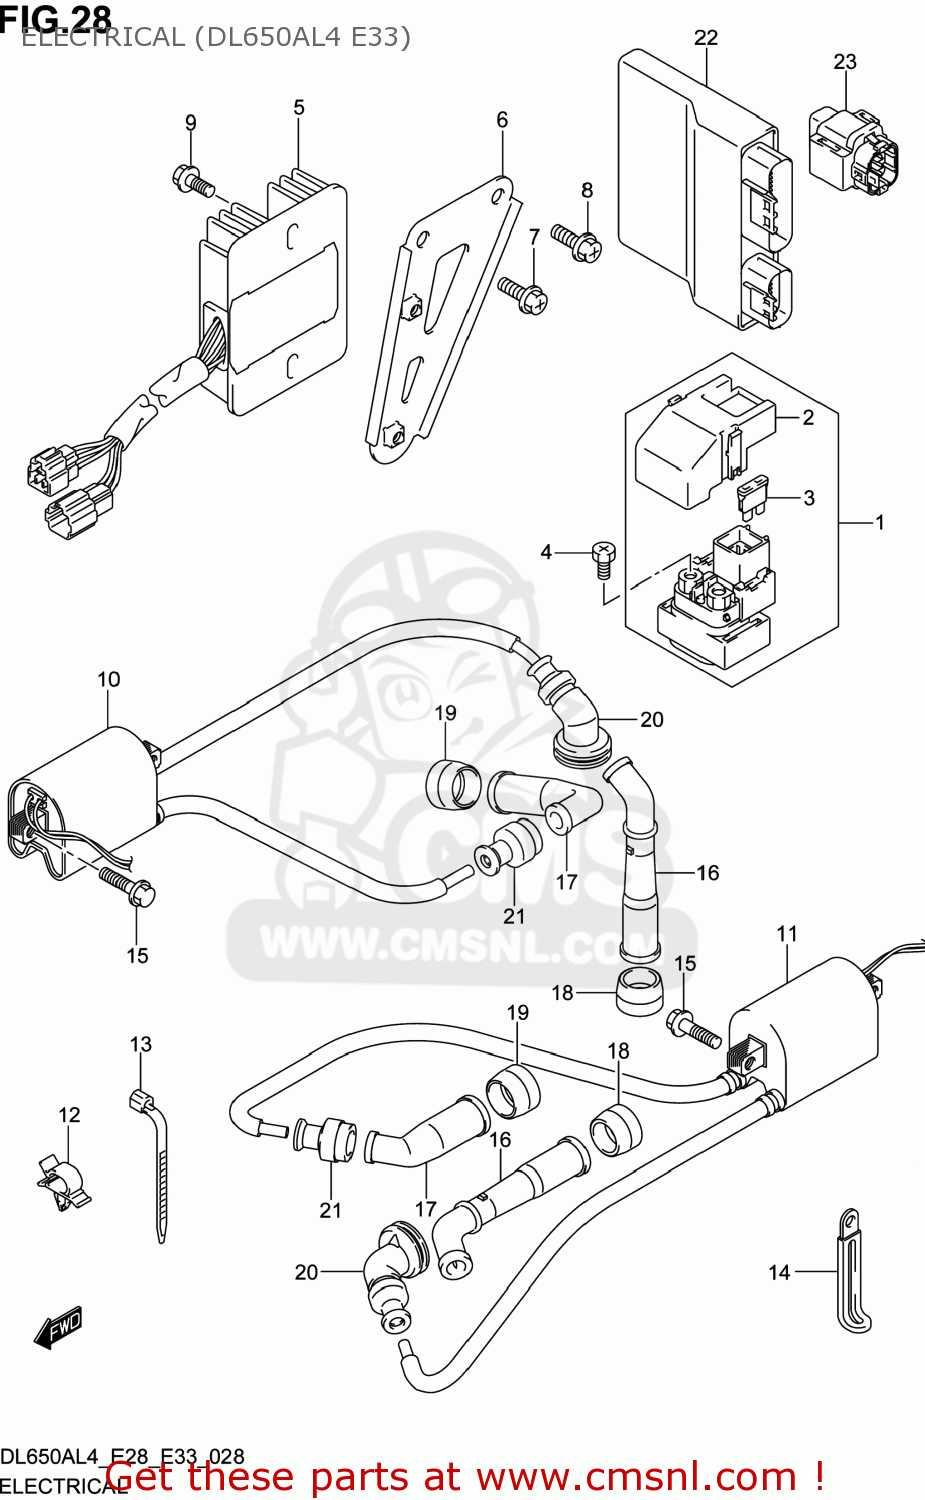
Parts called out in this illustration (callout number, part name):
1	RELAY ASSY,STARTING MOTOR
2	COVER
3	FUSE(30A)
4	SCREW(6X8)
5	RECTIFIER ASSY
6	BRACKET,RECT FTG
7	SCREW
8	SCREW
9	SCREW
10	COIL ASSY,IGNITION FR
11	COIL ASSY,IGNITION RR
12	CLAMP
13	CLAMP(L:165)
14	CLAMP(L:45)
15	BOLT
16	CAP ASSY,SPARK PLUG
17	CAP ASSY,SPARK PLUG
18	SEAL,SPARK PLUG
19	SEAL,SPARK PLUG
20	SEAL,HIGH TENSION CORD CTR
21	SEAL,HIGH TENSION CORD
22	CONTROL UNIT,FI
23	SENSOR ASSY,FUEL CUT
